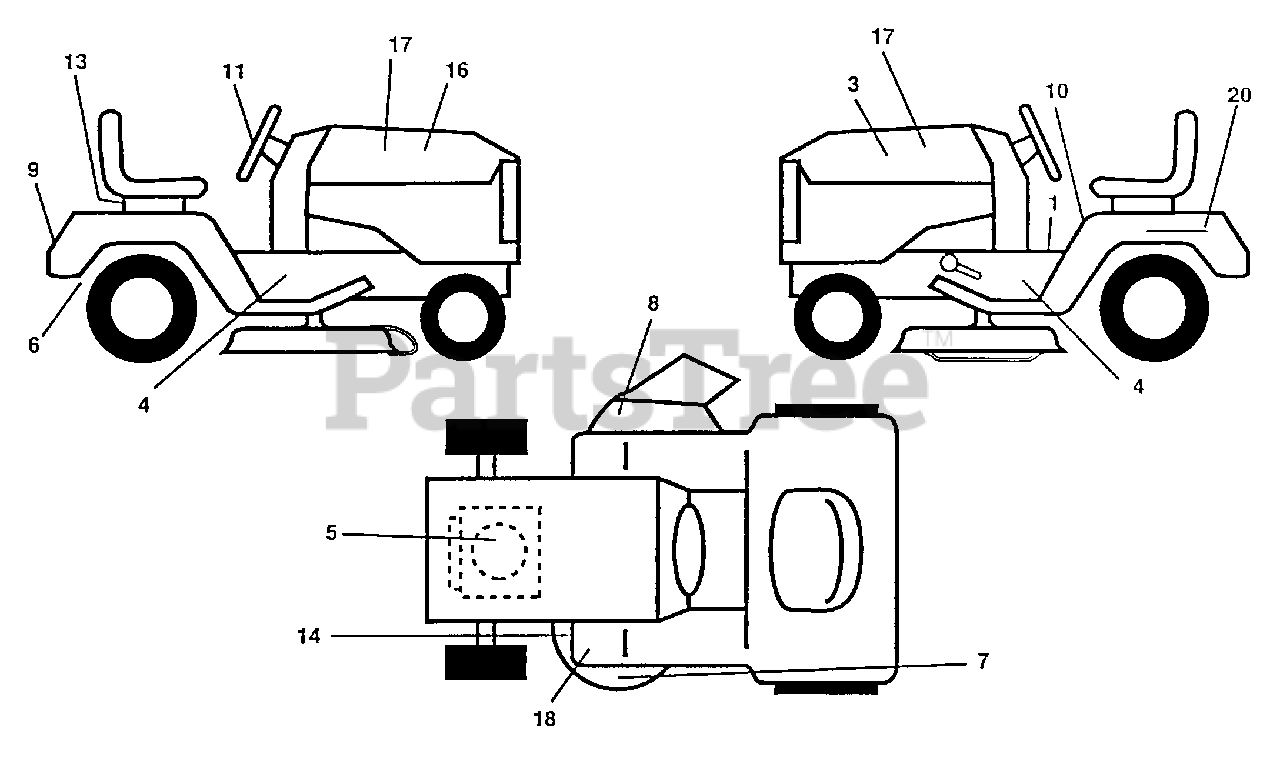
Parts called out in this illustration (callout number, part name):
1	Decal Saddle Oper. Inst.
3	Decal Hood LH
4	Decal Chassis
6	Decal Drawbar Cntrl MVT Hyd LT
7	Decal Mower Enviro
8	Decal Warning Mult-Language
9	Decal Fender (AYP part number)
10	Decal Fender Danger E/F
11	Decal Ins Strg Whl
13	Decal Cust Assist Poulan Pro
14	Decal V-Belt Schematic
16	Decal Hood RH
17	Decal Domed Poulan Pro
18	Decal Clutch/Brake Eng/Fr
20	Decal Bat Dan/Psn
